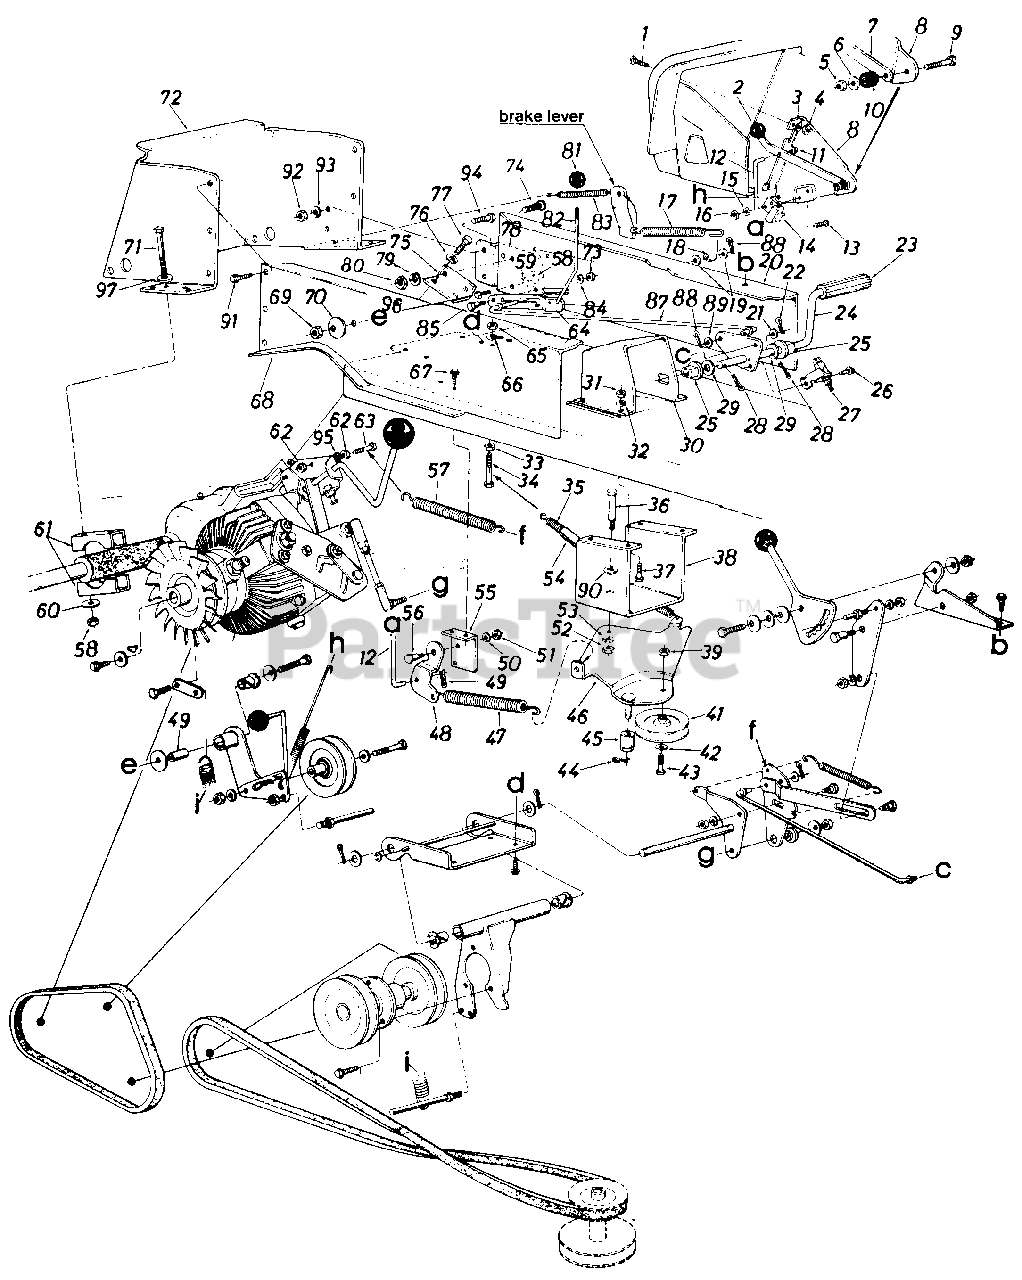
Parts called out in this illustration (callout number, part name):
1	Truss Mach. Scr. 1/4-20 x .50" Lg.
2	Knob-Blade Clutch
4	Hex Sems Nut 1/4-20 Thd.
5	Hex Cent. L-Nut 1/4-20 Thd.
6	Fl-Wash. 1/4" I.D. x .75" O.D.
7	PTO Lever
8	Deck Clutch Control Brkt.
9	Hex Bolt 1/4-20 x .75" Lg.
10	Rubber Wash. .33" I.D. x .87" O.D.
11	Push Cap 1/4" Rod
12	Deck Control Rod
13	Truss Mach. Scr. #10-24 x .50" Lg.
14	Safety Switch
15	Ext. L-Wash. #10 Scr.
16	Hex Nut #10-24 Thd.
17	Extension Spring .75" O.D. x 5 56n Lg.
18	Spacer 375n l.D. x .625" O.D. x .445" Lg.
19	Fl-Wash. .385" I.D. x .87" O.D.
20	Side Panel Upper Frame- L.H.
21	Fl-Wash. .385" I.D. x .87" O.D.
22	Cotter Pin 3/32" Dia. x .75"
23	Foot Pad
24	Foot Pedal Brkt. Ass'y.
25	Flange Brg. .630" I.D. x 1.25" O.D.
26	Hex Wash. Hd. S-Tap Scr. l/4-20 x .50n Lg.
27	Safety Switch
28	Cotter Pin 1/8" Dia. x 1.00"
29	Fl-Wash. .640" I.D. x .24" O.D.
30	Steering Gear Support Ass'y.
31	Fl-Wash. .385" I.D. x .87" O.D.
32	L-Wash. 5/16" I.D.
33	Hex Nut 1/4-20 Thd.
34	Hex Bolt 1/4-20 x 2.0" Lg.
35	Extension Spring .50" O.D. x 6.37" Lg.
36	Shld. Bolt 7/16" Dia. x .16"
37	Hex Bolt 5/16-18 x 1 oon
38	Idler Mtg. Brkt.Deck
39	Hex L-Nut 3/8-16 Thd.
41	"V"-Idler Pulley
42	Fl-Wash. 3/8" I.D.
43	Hex Bolt 3/8-16 x 1.75" Lg.
44	Cotter Pin 5/16" Rod
45	Spacer
46	Idler Brkt. Ass'y.
47	Extension Spring-Deck Control
48	Deck Control Pivot Brkt.
49	Cotter Pin 5/16" Rod
50	L-Wash. 5/16" I.D.
51	Hex Nut 5/16-18 Thd.*
52	Hex Nut 5/16-18 Thd.
53	L-Wash. 5/16" I.D.
54	Convoluted Conduit .50" I.D. x4" Lg.
55	Parking Brake Cam Mtg. Brkt.
56	Shld. Bolt 7/16" Dia. x .16"
57	Extension Spring
58	Hex Nut 3/8-16 Thd.
59	L-Wash. 3/8" I.D.
60	Bell-Wash .39" I.D. x 1.13"
61	Rear Axle Brkt.
62	Hex Nut 5/16-24 Thd.
63	Hex Scr. 5/16-24 x 1.5"
64	Parking Brake Cam
65	Hex Nut 1/4-20 Thd.
66	L-Wash. 1/4" I.D.
67	Hex Wash. Hd. S-Tap Scr. 1/4-20 x .50n Lg.
68	Side Panel Upper Frame- R.H.
69	Hex Nut 3/8-24 Thd.
70	Fl-Wash. .39" I.D. x 1.5" O.D.
71	Hex Bolt 3/8-16 x 3.50" Lg.
72	Hitch Plate
73	Hex Nut 3/8-16 Thd.
74	Rd. Hd. Ribbed Neck Bolt 3/8-24 x 1.0" Lg.
75	Mounting Brkt. Transaxle
76	L-Wash. 3/8" I.D.
77	Hex Bolt 3/8-16 x 1.00" Lg.(Grade 5)
78	Reinforcement Plate-Frame
79	L-Wash. 3/8" I.D.
80	Hex Nut 3/8-24 Thd.
81	Gear Shift Knob
82	Parking Brake Link
83	Extension Spring .38" O.D. x 3.18" Lg.
84	Hex Nut 3/8-16 Thd.
85	Shld. Bolt .500" Dia. x .170
87	Rod-Brake .38" Dia. x 19.3" Lg.
88	Cotter Pin 3/32" Dia. x .75"
89	Fl-Wash. .385" I.D. x .87"
90	Wave Wash.
91	Hex AB-Tap Scr. 5/16 x .75"
92	Hex Nut 5/16-24 Thd.
93	L-Wash. 5/16" I.D.
94	Hex Bolt 5/16-24 x .75" Lg.
95	L-Wash. 5/16" I.D.
96	Hex Bolt 3/8-16 x .75" Lg.
97	Fl-Wash. .385"1.D. x .870" O.D.
